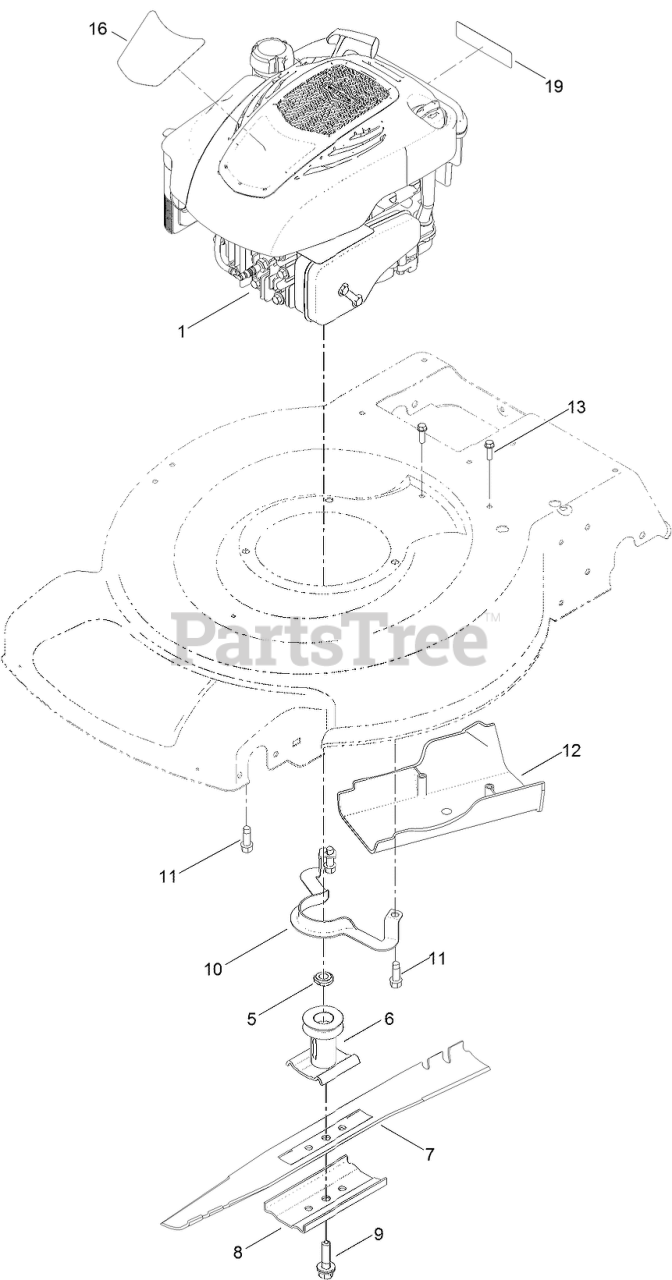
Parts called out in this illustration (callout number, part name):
5	Spacer-Driver
6	DRIVER-BLADE
7	BLADE-22 INCH
8	SUPPORT-BLADE
9	BOLT-BLADE
10	Guide-Belt
11	SCREW-TAPTITE
12	COVER-BELT
13	SCREW-HWH
16	DECAL-SHROUD
19	DECAL-ARRESTER, SPARK
